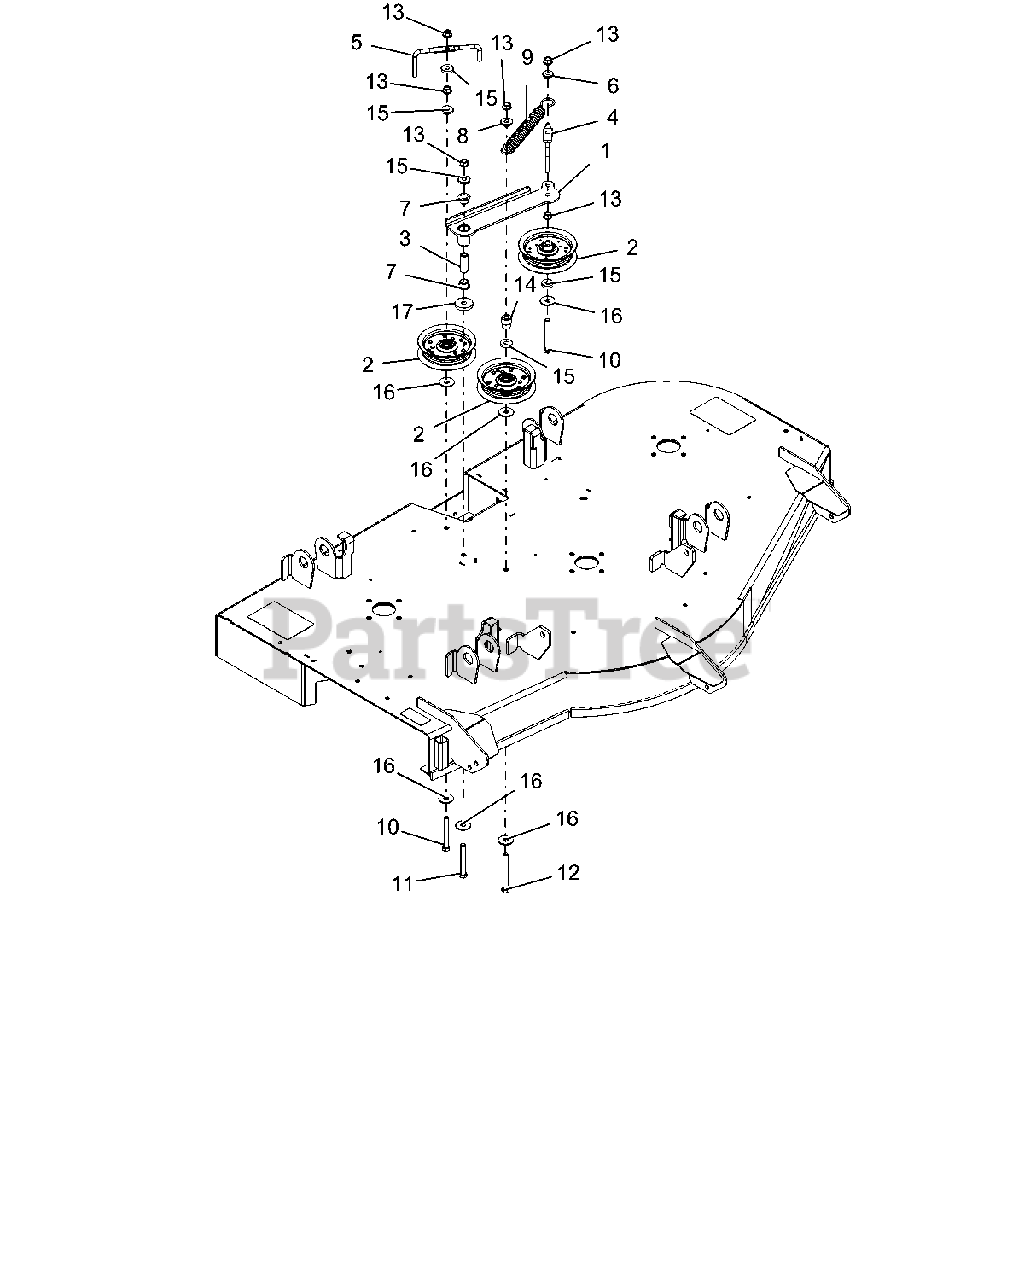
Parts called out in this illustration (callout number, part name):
1	WLDMT, IDLER ARM-52"
2	ASM, IDLER 4"
3	SPACER, .375IDX.625ODX1.66 PM
4	WIREFORM, BELT FINGER
5	WIREFORM, BELT FINGER
6	BSHG-FLG .385X.500X.875X.406
7	BSHG-FLG, .625X.750X.500X1.00
8	BSHG-FLG .385X.500X.875X.31
9	SG-TENS .135X.98X6.0 WLD 62
10	BLT-HEX .38-16X3.00 GR5 FTH YZ
11	BLT-HEX .38-16X3.00 GR5 FTH YZ
12	@BLT-HEX .38-16X3.50 GR5 YWZC
13	@NUT-LK-TOP-FLG .38-16 YWZC
14	BUSHING, IDLER (P/M)
15	WSHR-FL-STL .406X1.00X.188 YWZ
16	@WSHR-FL-STL .406X1.25X.10 ZC
17	WSHR,FLT STL.406X1.50X.245YWZC
